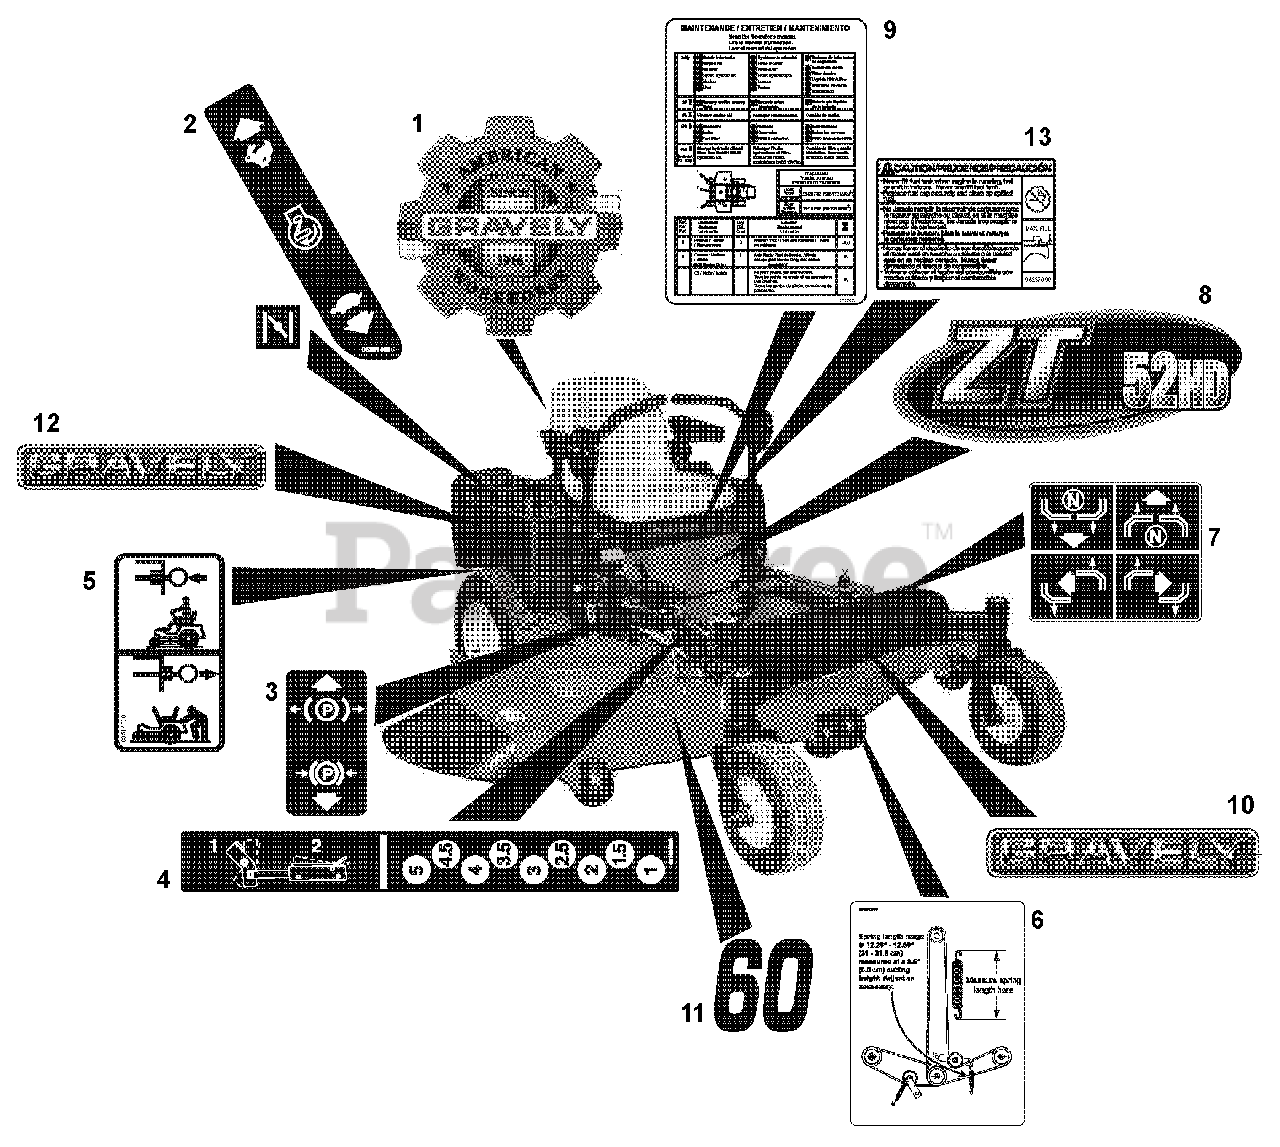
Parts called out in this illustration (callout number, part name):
1	Decal, Gravely Heritage Small
2	Decal, Control
3	Decal, Parking Brake Lever
4	Decal, Height of Cut
5	Decal, Transmission Disconnect
6	Decal, Belt Diagram
7	Decal, Instructional Steering
8	Decal, 44 HD (991090)
8	Decal, 48 HD (991082)
8	Decal, 52 HD (991083)
8	Decal, 60 HD (991084, 091)
9	Decal, Maintenance Instructions
10	Decal, 15" Gravely Logo
11	Decal, 60" (991084, 091)
11	Decal, 52" (991083)
11	Decal, 48" (991082)
11	Decal, 44" (991090)
12	Decal, Fuel Tank Gravely
13	Decal, Fuel Warning
